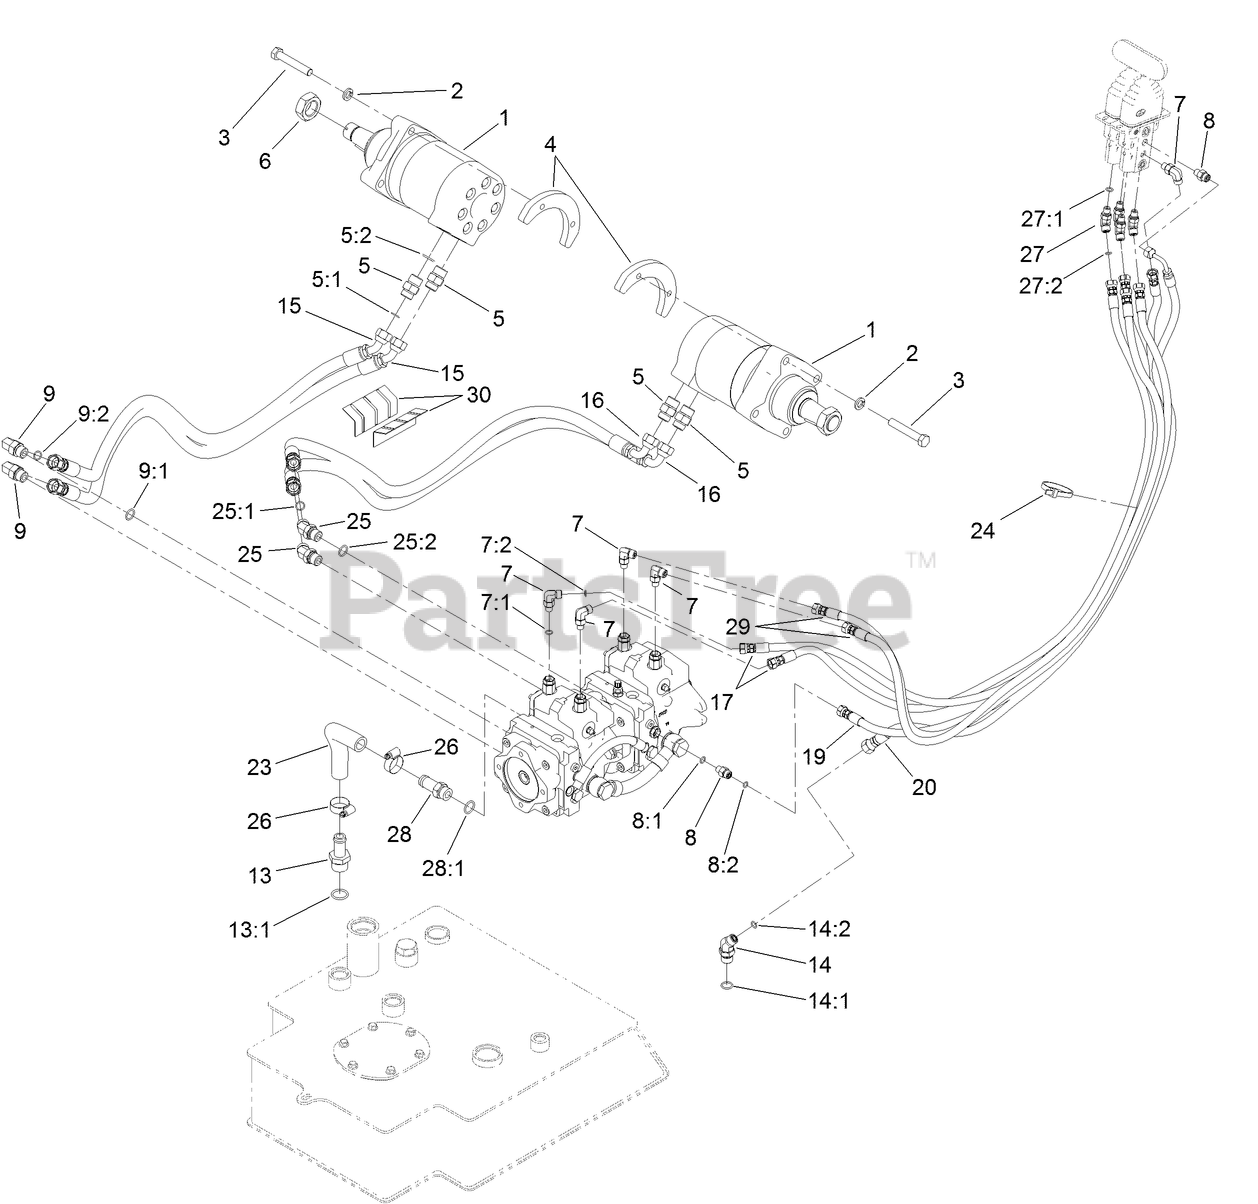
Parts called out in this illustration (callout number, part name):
1	MOTOR-HYD
2	WASHER-LOCK
3	SCREW-HH, TAP
4	PLATE-MOUNTING
5	FITTING-STRAIGHT
5:1	O-RING
5:2	O-RING
6	NUT-HEX
7	FITTING-90 DEG
7:1	O-RING
7:2	O-RING
8	FITTING-STRAIGHT
8:1	O-RING
8:2	O-RING
9	FITTING-ELBOW-90 DEG
9:1	O-RING
9:2	O-RING
13	FITTING-STRAIGHT
13:1	O-RING
14	FITTING-HYD, 45 DEG
14:1	O-RING
14:2	O-RING
15	HOSE-HYD
16	HOSE-HYD
17	HOSE-HYD
19	HOSE-HYD
20	HOSE-RETURN
23	HOSE-RETURN
24	TIE-CABLE
25	FITTING-HYD, 45 DEG
25:1	O-RING
25:2	O-RING
26	CLAMP-HOSE
27	FITTING-HYD, 45 DEG
27:1	O-RING
27:2	O-RING
28	FITTING-STR
28:1	O-RING
29	HOSE-HYD
30	PROTECTOR-HOSE
